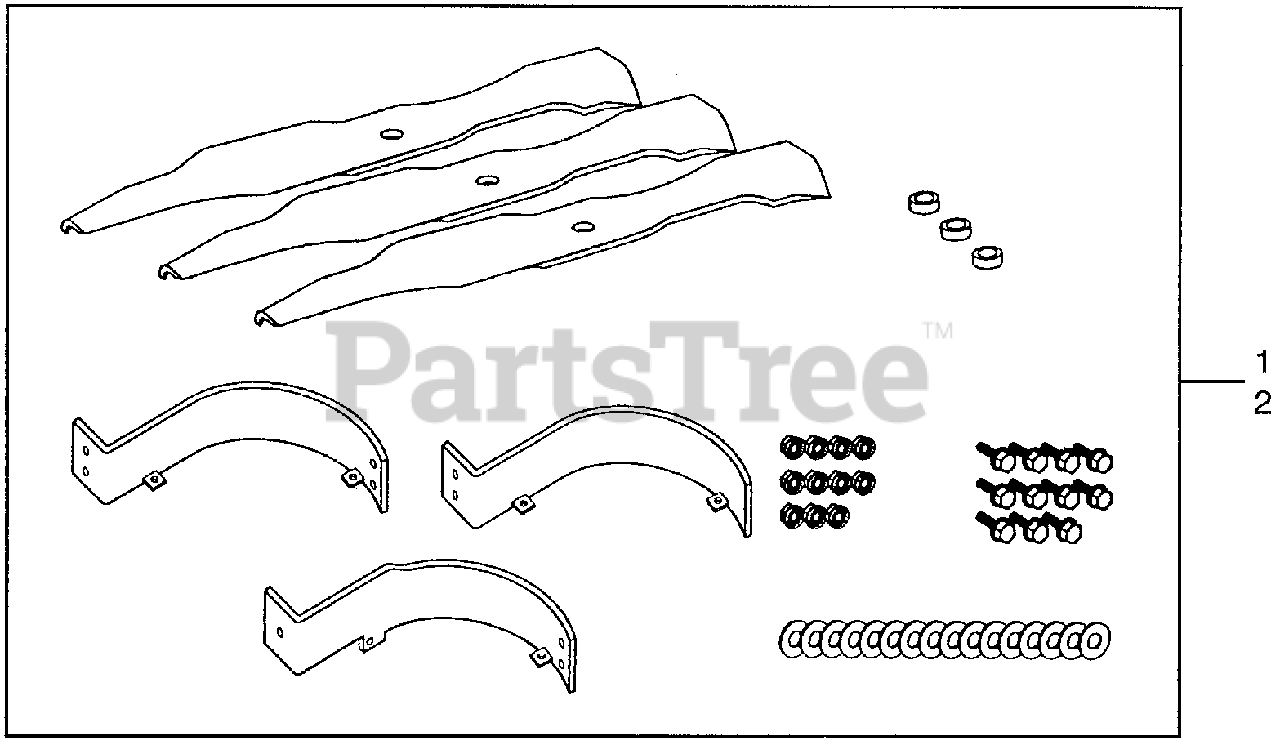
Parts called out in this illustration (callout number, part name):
1	MULCH KIT (52")
2	MULCH KIT (60")
NI	CATCHER (LESS BAG)
